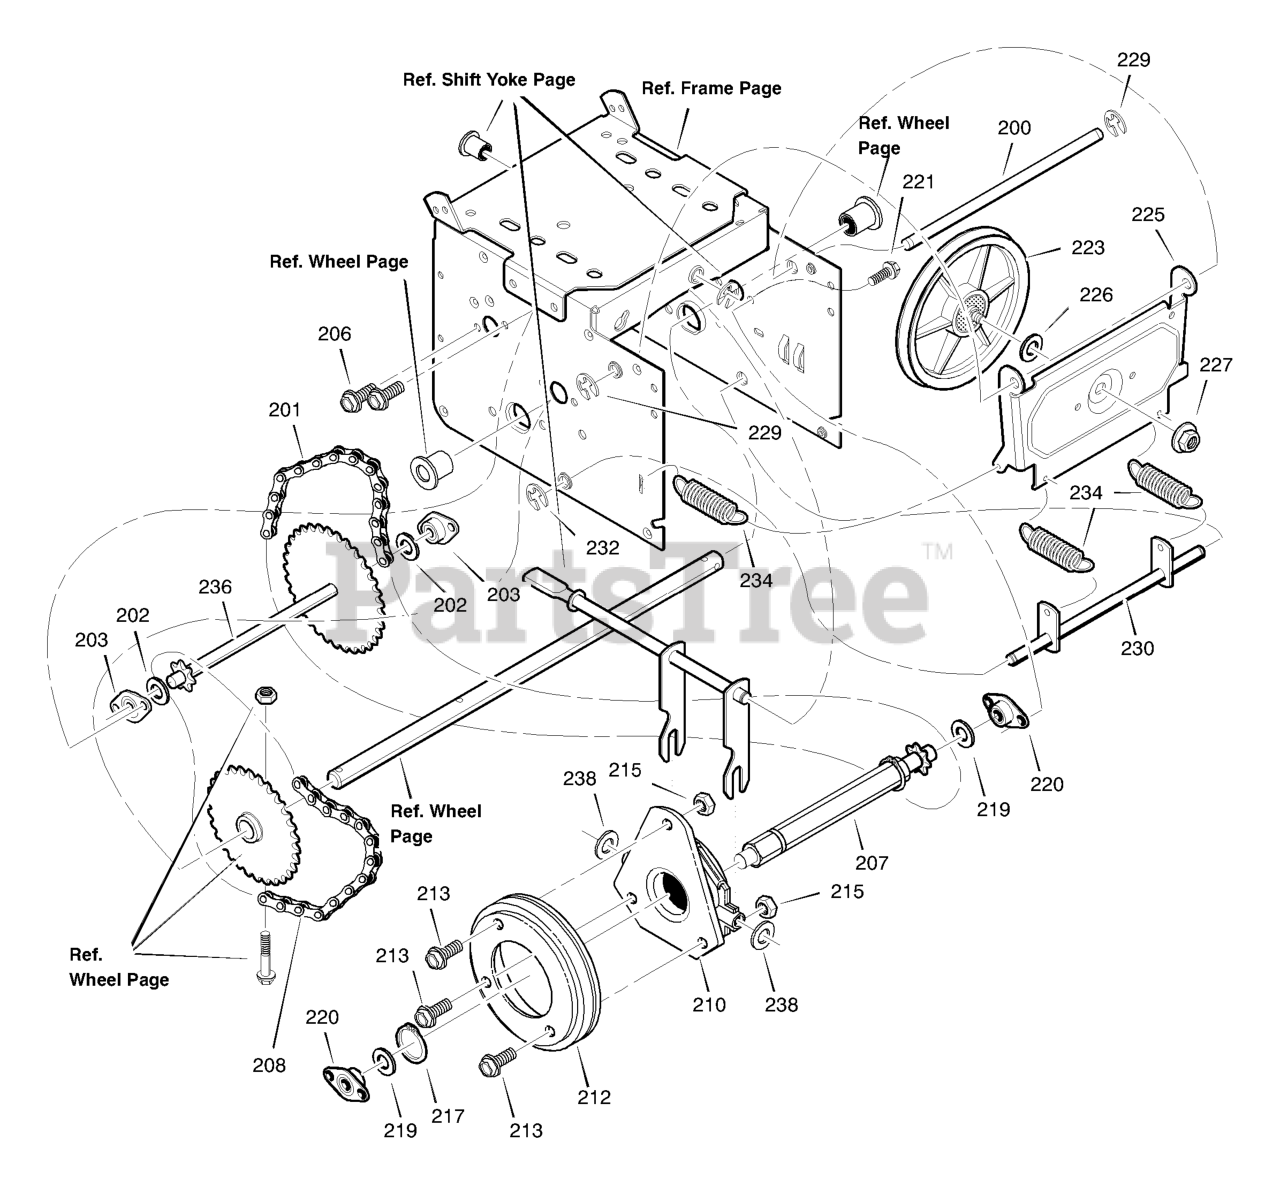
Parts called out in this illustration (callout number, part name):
200	LF AXLE, SWING PLATE YZ
201	CHAIN, ROLLER #420x19.00
202	BEARING, BALL
203	RETAINER, BEARING
206	SCREW, TAP 5/16-18 x 0.5
207	ASSY, HEX SHAFT
208	CHAIN, ROLLER #420x18.00 LG
210	BEARING, TRUNION CLUTCH R
212	WHEEL, FRICTION DISC
215	NUT, KEPS HEX 1/4-20
217	RING, RETEXT
219	BEARING, BALL
220	RETAINER, BEARING
221	SCREW, TAP 5/16-18 x .5
223	FRICTION PULLEY
225	LF PLATE, SWINGING YZ
226	SPACER, FRICTION PULLEY
227	NUT, FLANGE LOCK 3/8-24
229	RETAINER, RING
230	LF ASSY, SPRING LINK YZ
232	RETAINER, RING
234	SPRING, EXTENSION
236	WLD, INTERMED SPROCKET 33T/7
238	WASHER, FLAT
